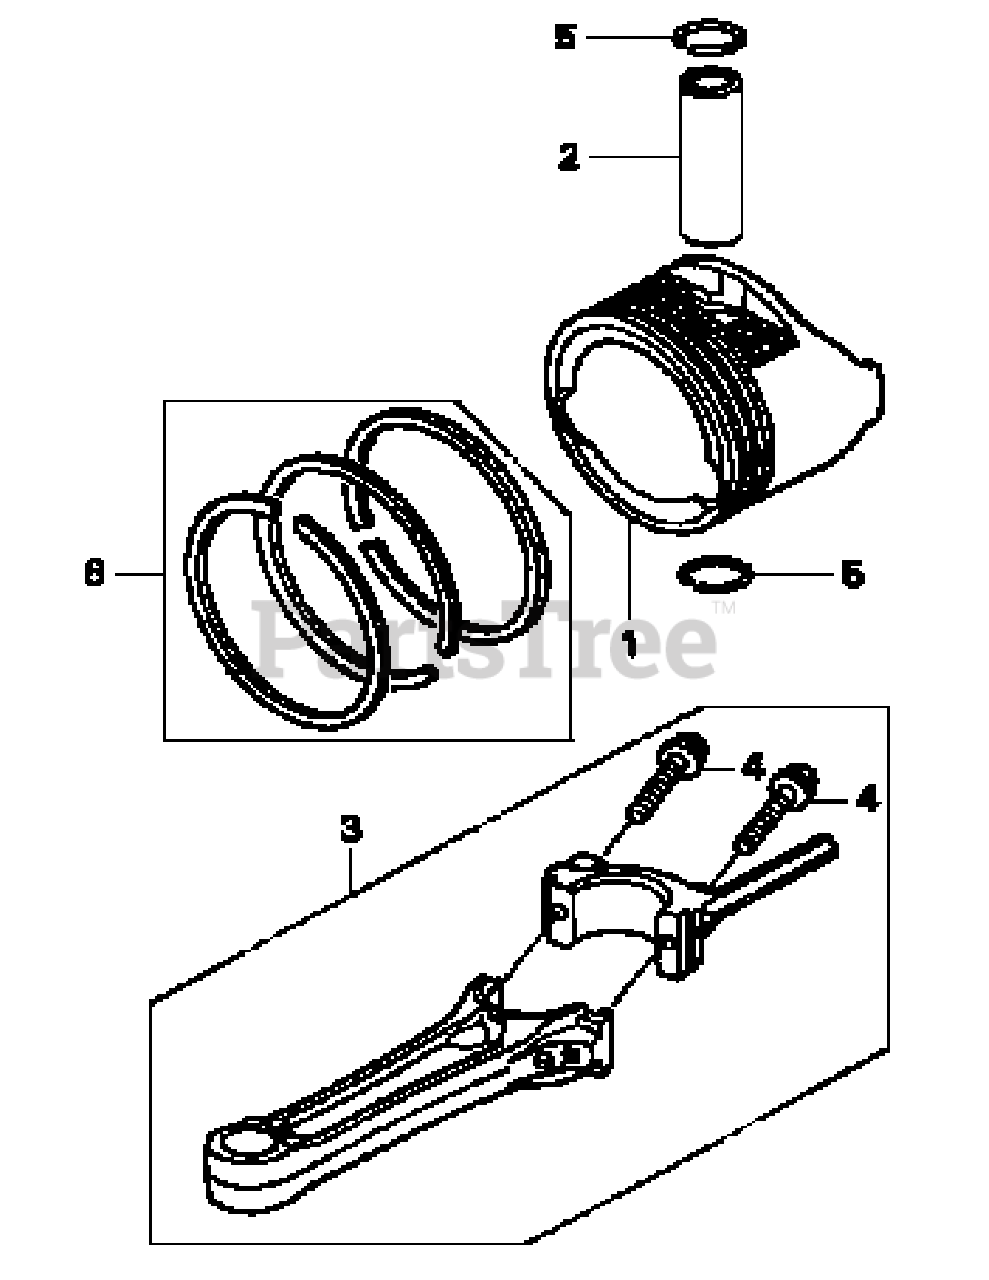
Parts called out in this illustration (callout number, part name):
2	Piston Pin
3	Connecting Rod Assy.
4	Connecting Rod Bolt
5	Piston Pin Clip (13mm)
6	Piston Ring Set
